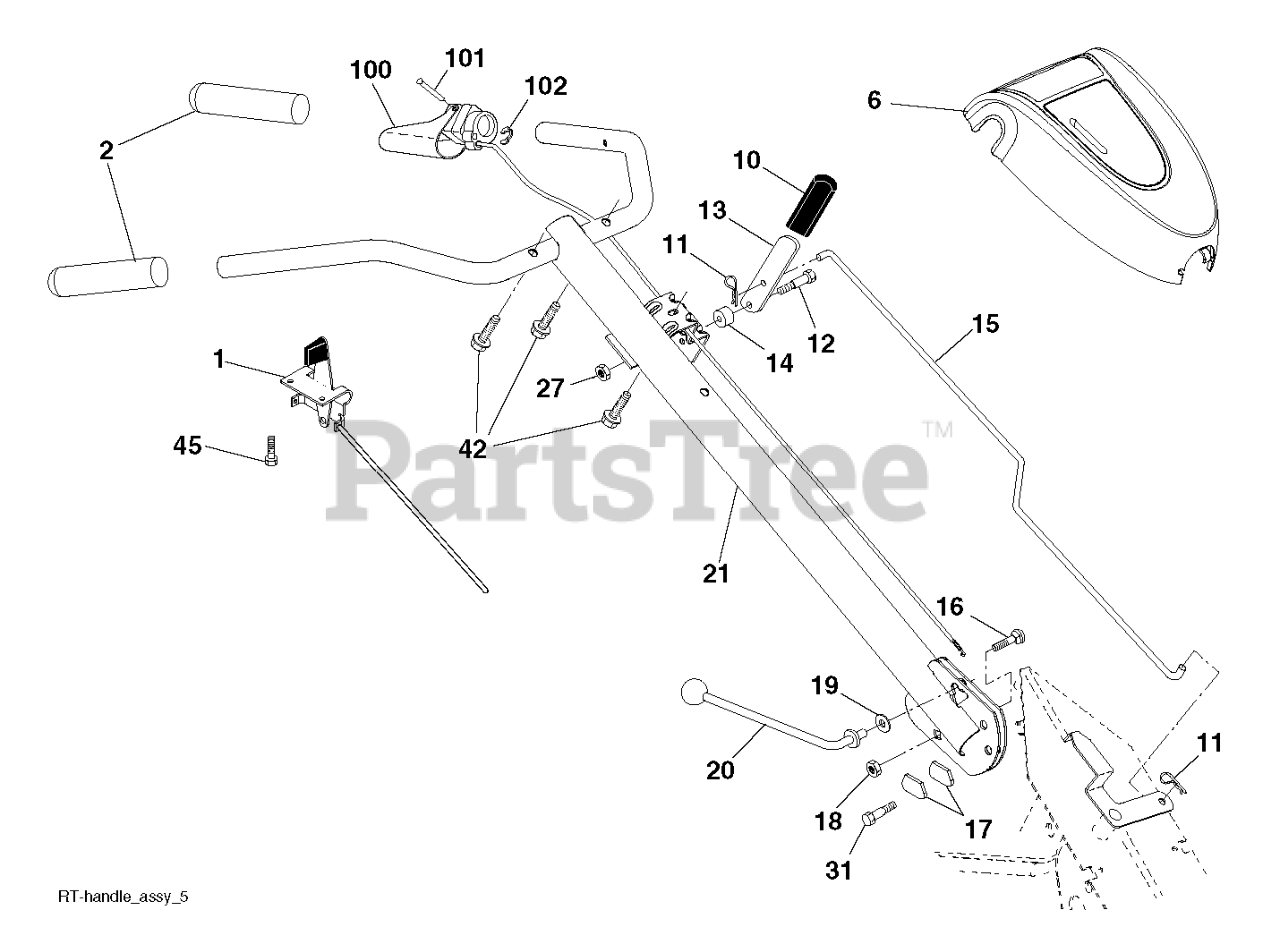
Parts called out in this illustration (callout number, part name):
1	CABLE ASSY THROTTLE
2	GRIP.1X5.06
6	CONSOLE HUSQVARNA W/THROTTLE T
10	GRIP T
11	RETAINER M
12	SHOULDER BOLT ST
13	HANDLE
14	GROMMET.RUBBER.CRT.TILLER
15	ROD SHIFT RT UNIVERSAL
16	BOLT D
17	LOCK.HANDLE.CRT
19	WASHER CRT
20	LEVER.LOCK.CRT
21	HANDLE.ASM.HUSQ/P.PRO.GREY
27	NUT T
31	BOLT.PIVOT
42	SCREW.#10 X 0.750.BOS
45	SCREW.#10 X 0.500
100	CONTROL.ASSEMBLY.TINE.TILLER
101	PIN, PIVOT
102	RETAINING.RING.#5103-25
